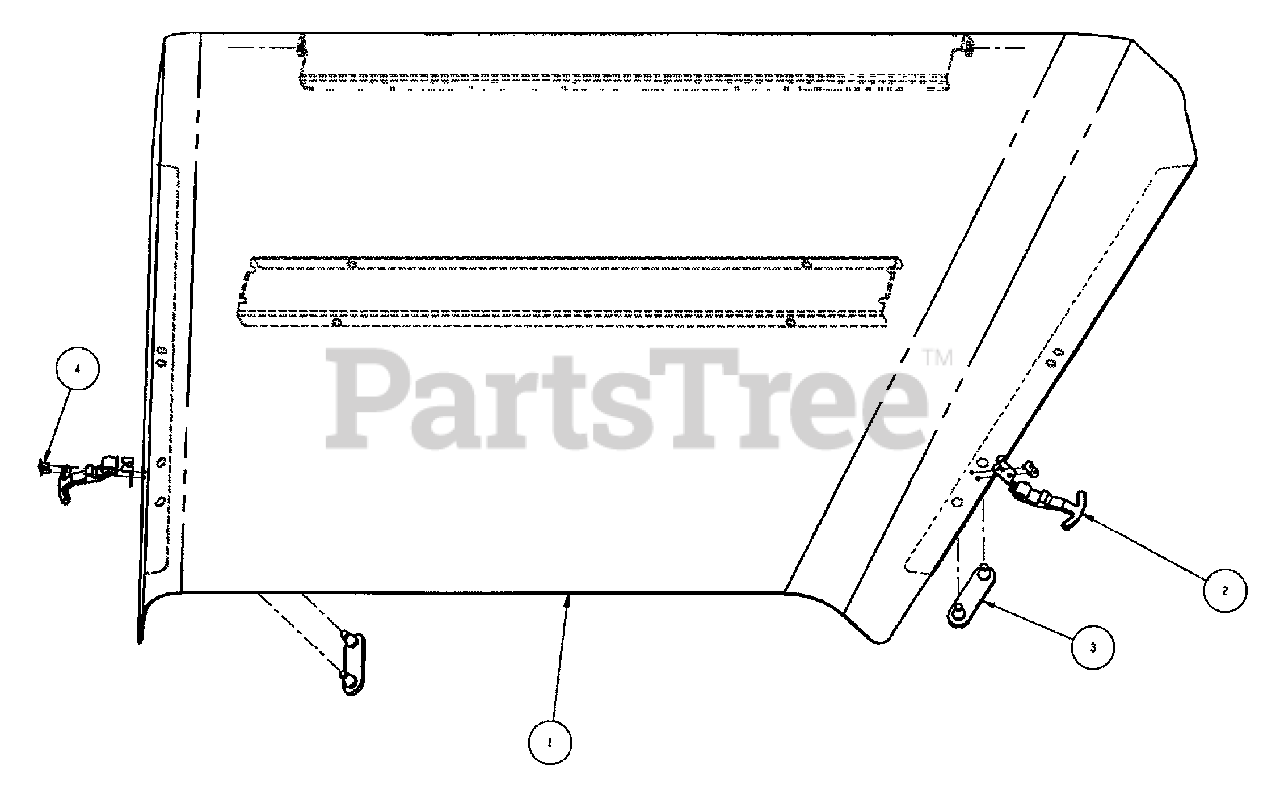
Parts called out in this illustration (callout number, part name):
1	HOOD WELDMENT
2	STRAP, RUBBER T-HANDLE
3	BUMPER, RUBBER
4	RIVET, 1/8 X 3/8
